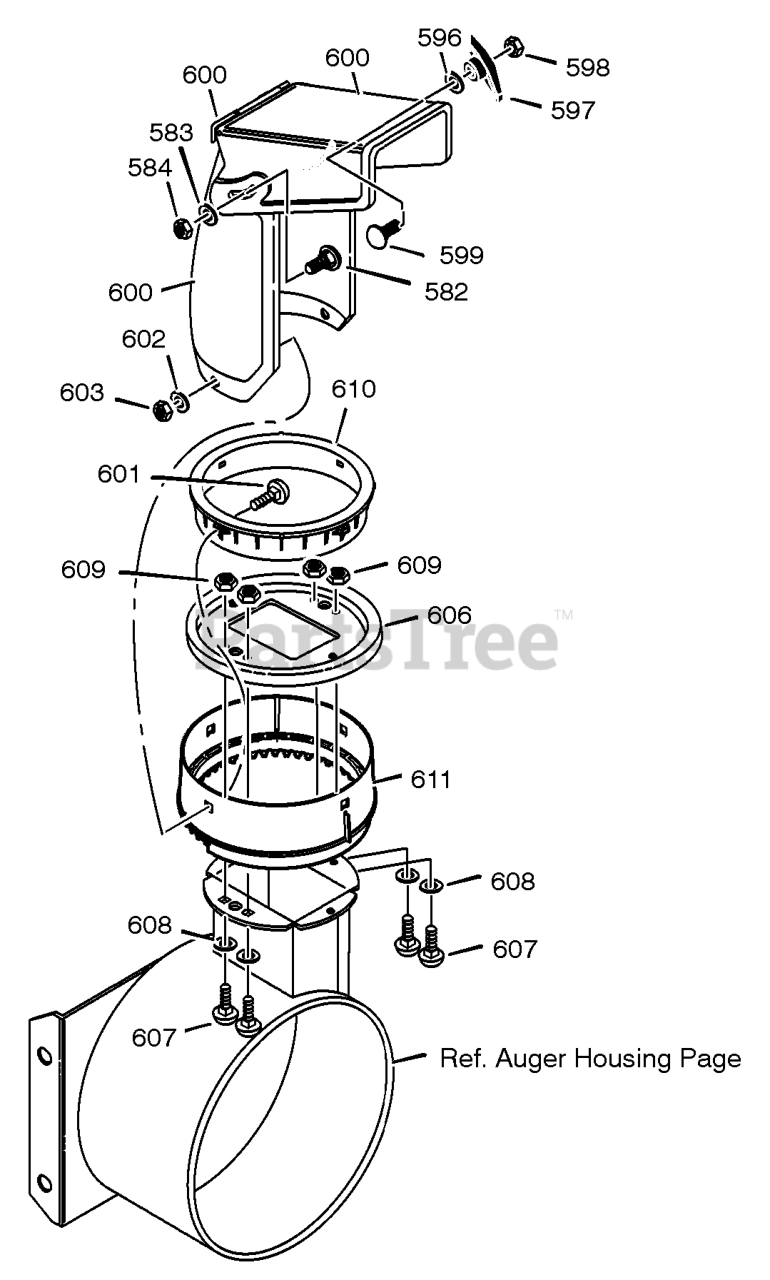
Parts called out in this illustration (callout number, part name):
582	SCREW, 5/16-18 x 0.75
583	WASHER, FLAT
584	NUT, 5/16-18 REGHEXCTRLK
596	WASHER
597	KNOB, T 3.00
598	NUT, 5/16-18 REGHEX
599	BOLT, 5/16-18X1.125
600	CHUTE ASSEMBLY
601	BOLT, 5/16-18 X1.00
602	WASHER, FLAT
603	NUT, 5/16-18 HEXNYL
606	CHUTE COLLAR
607	SCREW, 1/4-20 X 1.00
608	WASHER, FLAT
609	NUT, 1/4-20 HEX NYLOCK
610	RETAINER RING INNER
611	RETAINER RING OUTER
